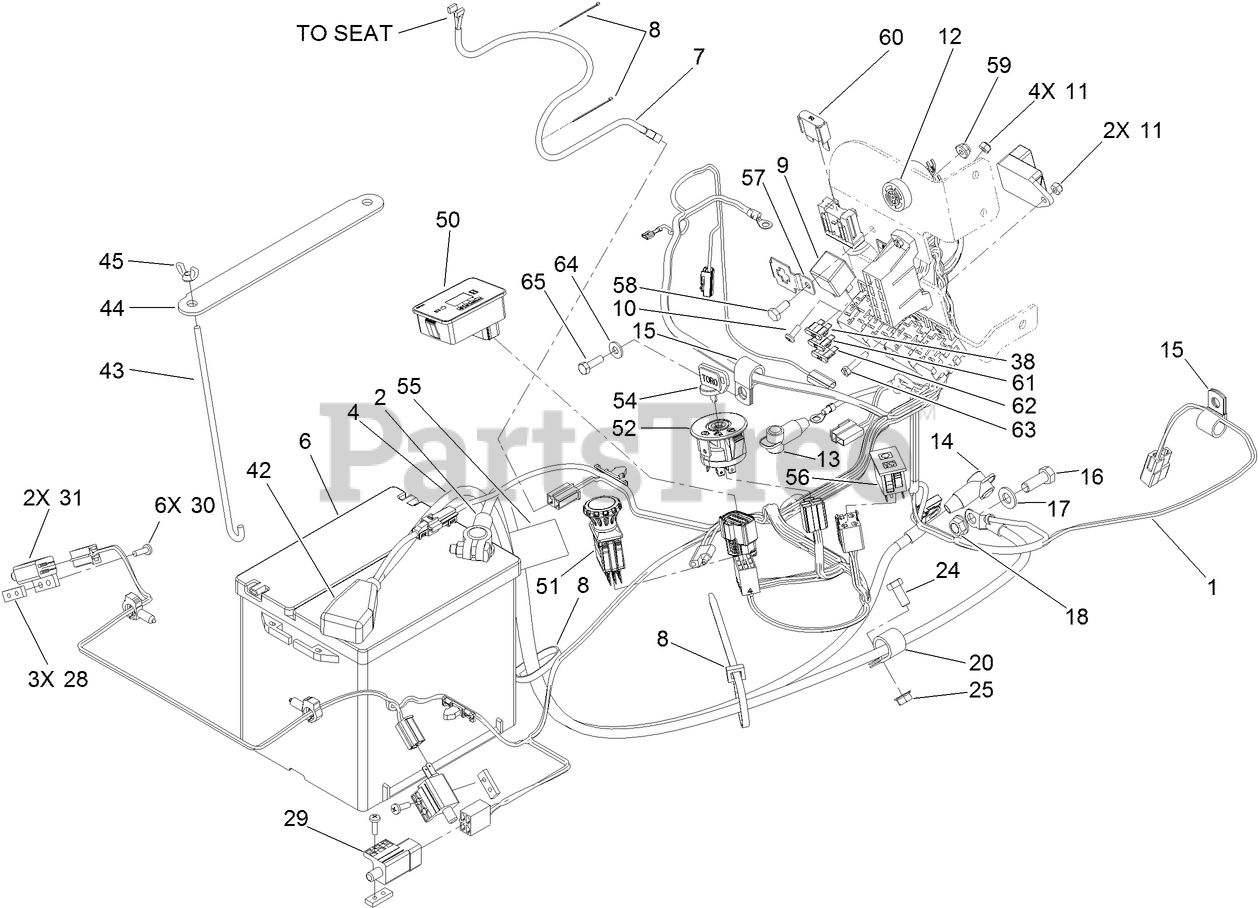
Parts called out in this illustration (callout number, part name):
1	HARNESS-ELECTRICAL
2	CABLE-BATTERY, NEGATIVE
4	CABLE-STARTER
6	BATTERY-DRY
7	HARNESS-WIRING, SEAT
8	TIE-PLASTIC
11	NUT-LOCK, NI
12	ALARM-TONE, DUAL
13	CAP-INSULATOR, RED
14	INSULATOR-STARTER
15	CLIP-LOOM
16	SCREW-HH
17	WASHER-FLAT
18	NUT-HHF, WHIZ
20	CLIP-LOOM
24	SCREW-HH
25	NUT-HF
28	PLATE-TAPPED
29	SWITCH
30	SCREW-PPH
31	SWITCH-OPEN, NORMALLY
38	FUSE-BLADE TYPE, 20 AMP
42	INSULATOR-TERMINAL, BATTERY
43	Bolt-Holddown
44	HOLDDOWN-BATTERY
45	WINGNUT
50	MODULE ASM
51	SWITCH-PTO, 10 AMP
52	SWITCH-IGNITION
54	KEY-IGNITION
55	DECAL-INSTRUCTIONS, CHARGING
56	LAMP-WARNING
57	CLIP-FUSE
58	SCREW-HH
59	NUT-HF
60	FUSE-BLADE, 50 AMP
61	FUSE-BLADE, 10 AMP
62	FUSE-BLADE, 30 AMP
64	WASHER-FLAT
65	SCREW-HH
